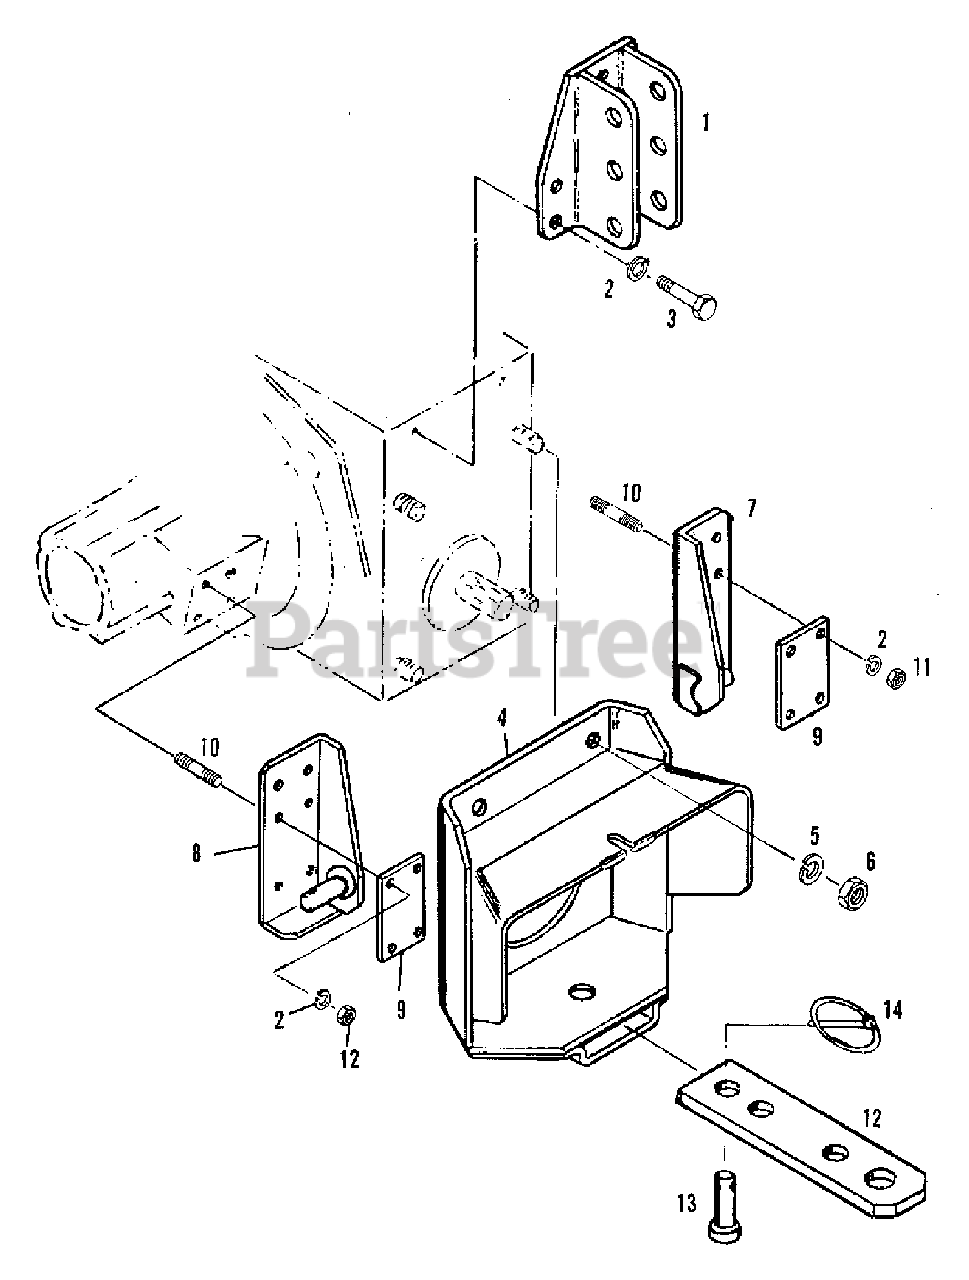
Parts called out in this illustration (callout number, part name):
1	MOUNTING, upper link
2	LOCKWASHER, M12
4	GUARD, P.T.O.
5	LOCKWASHER, M16
7	MOUNTING, R.H., lower link
8	MOUNTING, L.H., lower link
13	PIN, drawbar
14	PIN, quick
